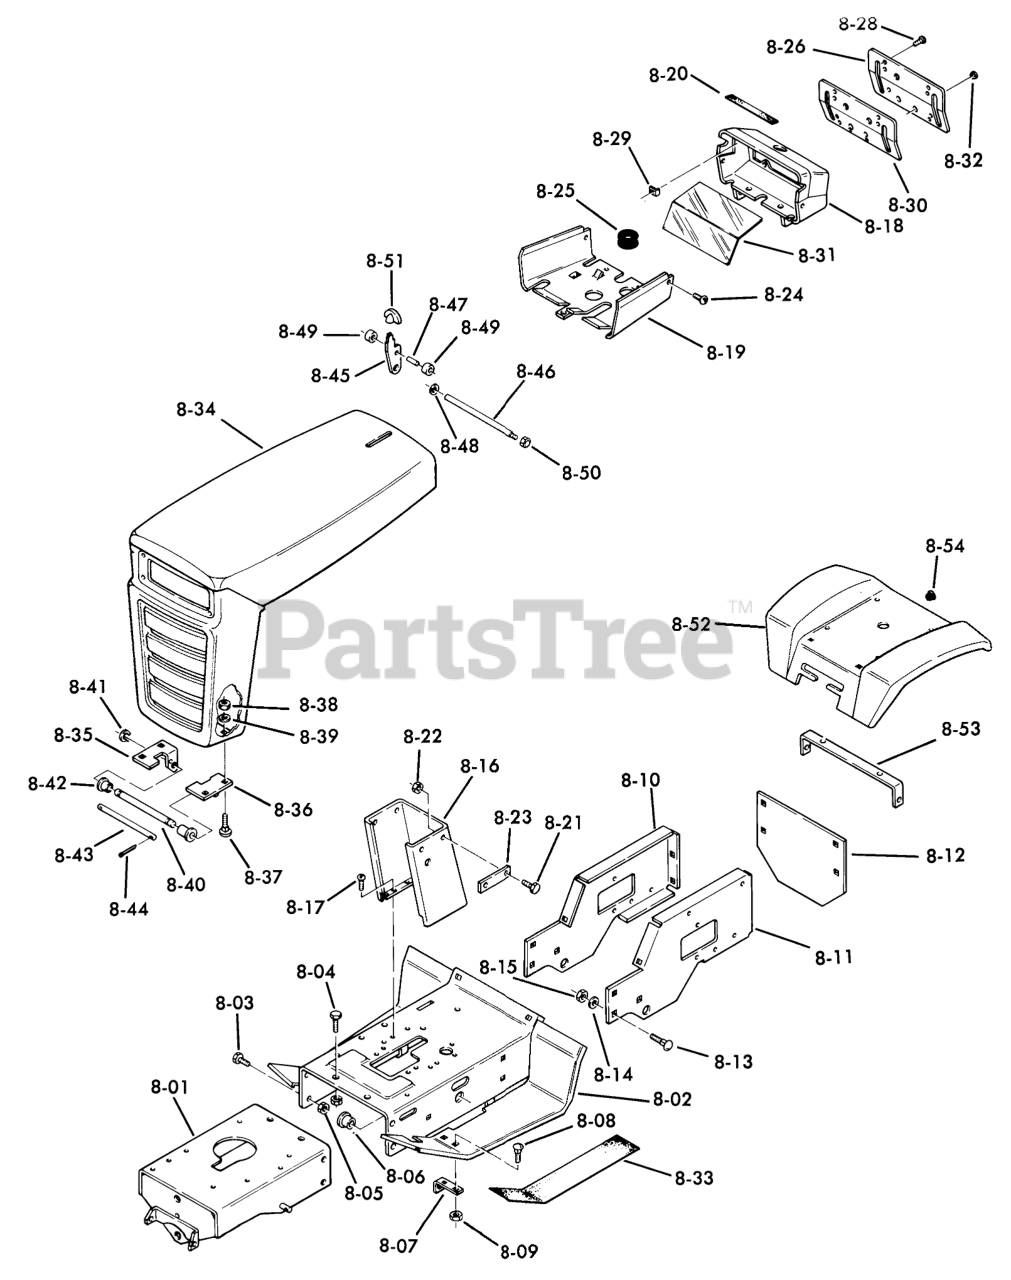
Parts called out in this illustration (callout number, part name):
1	Assy-Frame Front
2	Assy-Frame Center (W/Bushing)
3	Bolt
4	Bolt
5	Nut
6	Bushing
7	Bracket
8	Bolt
9	Nut
10	Panel-Side-R.H.
11	L.H. Side Panel
12	Panel-Rear
13	Bolt-Carriage
14	Washer
15	Nut
16	Thrust Washer
17	SCREW
18	Housing
19	Support-Tank
20	Tape
21	Screw
22	Nut
23	Spacer
24	Screw
25	Grommet
26	Dash Panel
28	SCREW BLACK
29	SPEED NUT
30	BACK UP PLATE
31	CONTROL PROTECTOR
32	PLUG BUTTON
33	PAD-FOOTREST
34	Hood
34	Assy-Hood & Grill
35	Bracket-Grill Pivot RH
36	Bracket-Grill Pivot LH
37	Bolt
38	Nut
39	WASHER 5/16 SAE
40	Rod-Pivot
41	E Ring-3/8
42	NYLINER BUSHING
43	ROD PIVOT STOP
44	Cotter Pin
45	LEVER HOOD LATCH
46	Rod Latch
47	SPIROL PIN
48	SPEED NUT
49	Roller
51	KNOB
52	Assy-Fender & Plate
52	Bolt
53	Fender Support
54	Bushing
